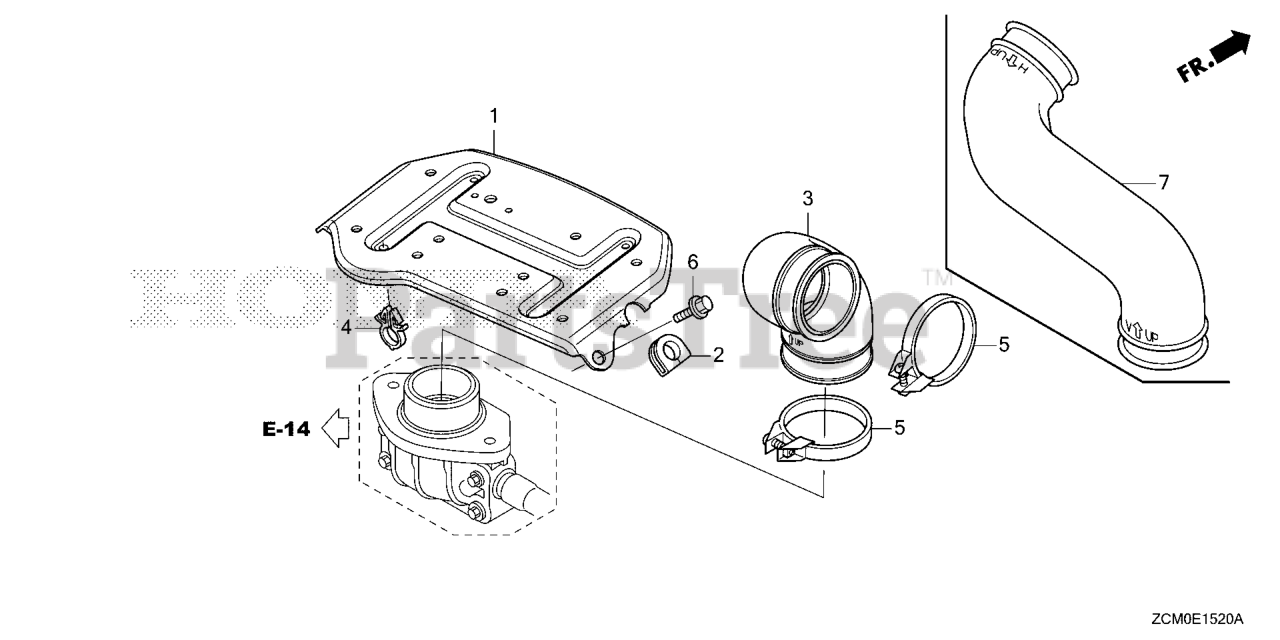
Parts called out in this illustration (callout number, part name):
1	STAY, AIR CLEANER
2	GROMMET, AIR CLEANER STAY
4	CLIP, WIRE HARNESS
6	BOLT, FLANGE (8X16) Use from Engine SN 1000016.
